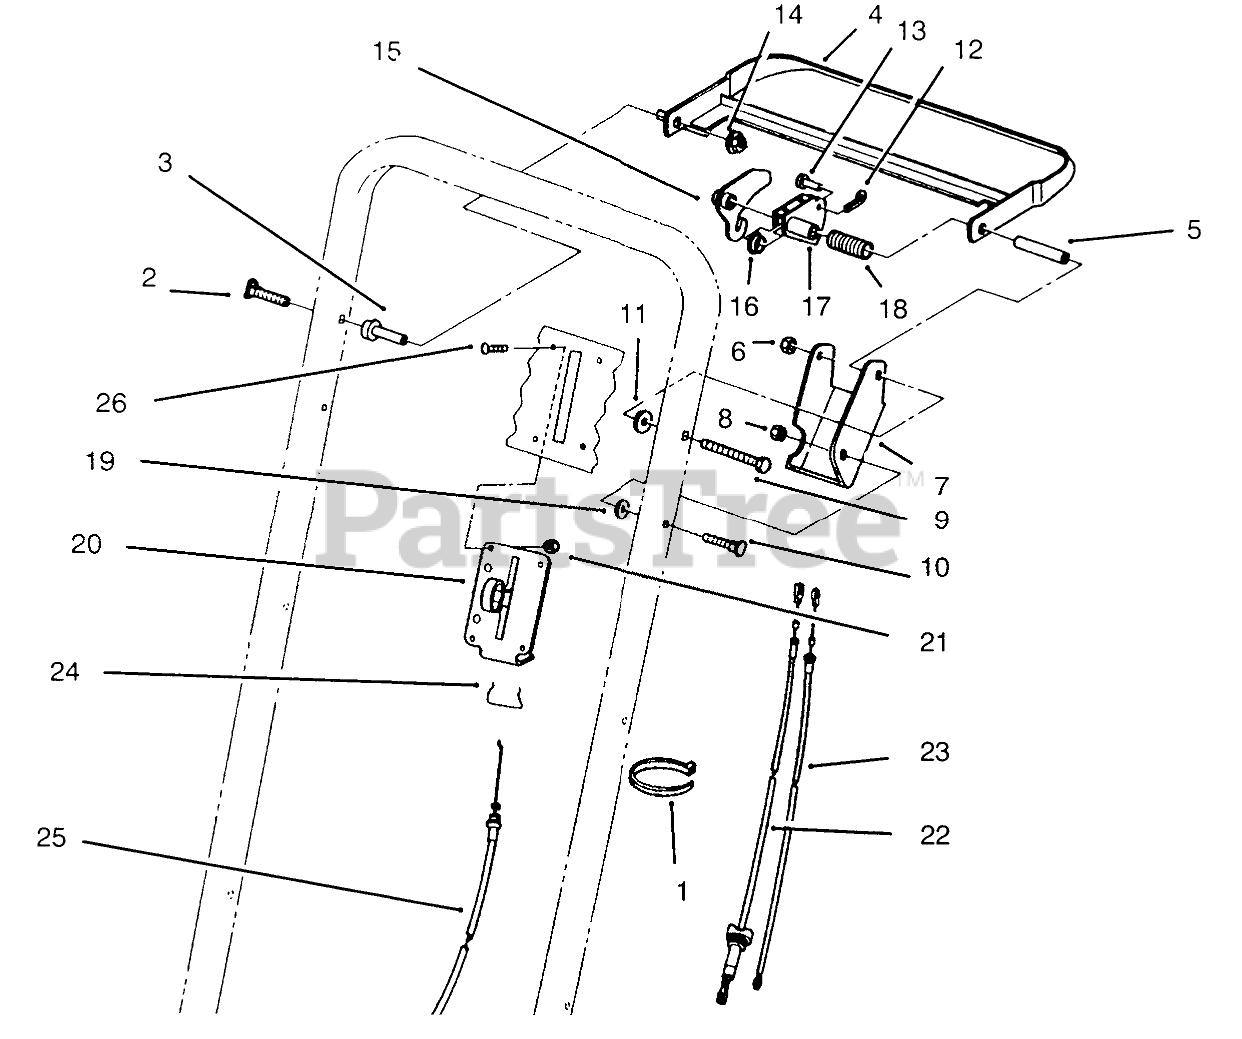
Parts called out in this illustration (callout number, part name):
1	TIE-CABLE
2	SCREW
3	SPACER-SUPPORT
4	Bar-Control
5	SPACER-BRACKET, CONTROL
6	NUT-LOCK, NI
7	Bracket-Control
8	NUT-LOCK, NI
9	SCREW-HH
10	SCREW-HANDLE
11	SPACER
12	PIN-COTTER
13	PIN-CABLE
14	NUT-LOCK, NI
15	LEVER-TRACTION
16	BUSHING-FLANGE
17	LEVER-BBC
18	SPRING-CONTROL
19	SPACER
20	CONTROL-THROTTLE
21	NUT-LOCK, NI
22	CABLE-TRACTION
23	CABLE-CLUTCH
24	RETAINER-CABLE, THROTTLE
25	THROTTLE CABLE
26	SCREW-PPH
